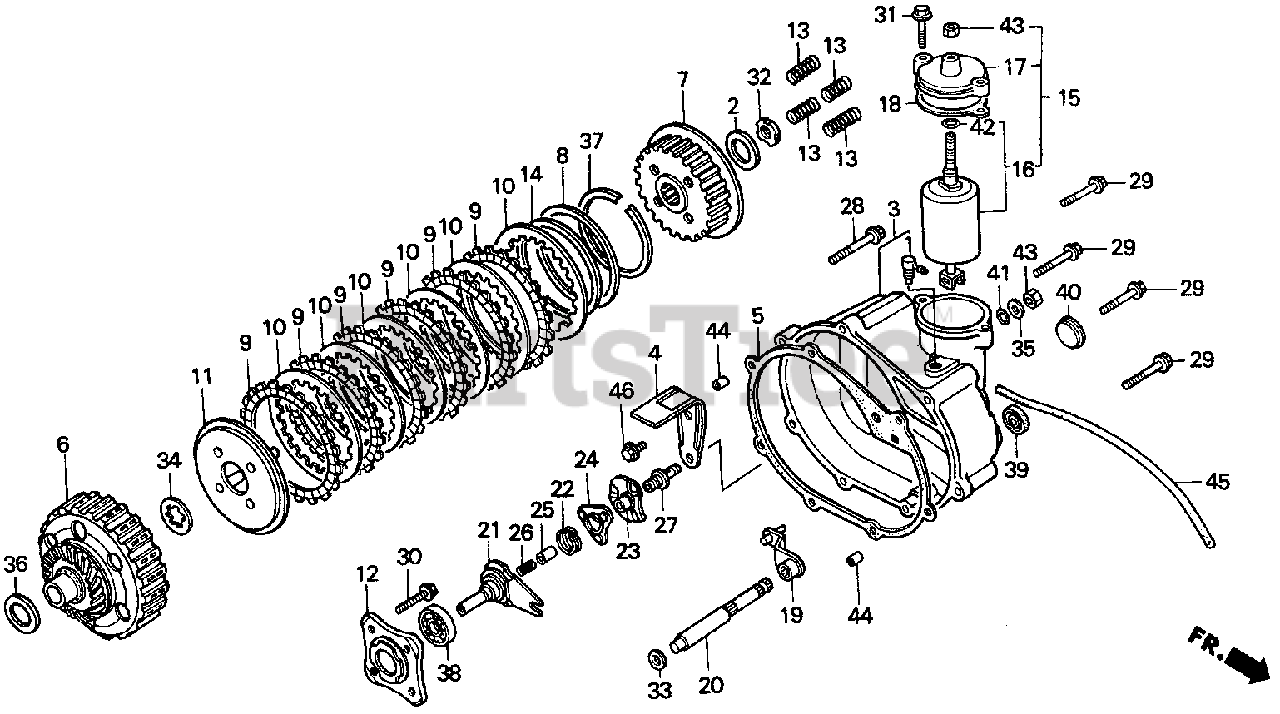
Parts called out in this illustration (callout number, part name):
1	JOINT, BREATHER
2	WASHER, OIL FILTER ROTOR LOCKING
3	COVER, CLUTCH
4	GUIDE, OIL
5	GASKET, CLUTCH COVER
6	CLUTCH (OUTER)
7	CENTER, CLUTCH
8	SEAT, JUDDER SPRING
9	DISK, CLUTCH FRICTION
10	PLATE, CLUTCH
11	PLATE, CLUTCH PRESSURE
12	PLATE, CLUTCH LIFTER
13	SPRING, CLUTCH
14	SPRING, CONED DISK
15	DAMPER SET, CLUTCH
16	DAMPER ASSY., CLUTCH
17	BRACKET, DAMPER (UPPER)
18	GASKET, CLUTCH DAMPER
19	LEVER, CLUTCH
20	SHAFT, CLUTCH
21	PLATE, CLUTCH CAM
22	SPRING, CAM PLATE SIDE
23	PLATE, CLUTCH LIFTER (NOT AVAILABLE)
24	RETAINER, CLUTCH BALL
25	THROUGH, OIL
26	SPRING, OIL THROUGH
27	BOLT, CLUTCH ADJUSTING
28	BOLT, FLANGE (6X40) (CT200)
29	BOLT, FLANGE (6X32) (CT200)
30	BOLT, SPECIAL FLANGE (6X28) (NOT AVAILABLE)
31	BOLT, FLANGE (6X25) (CT200)
32	NUT, LOCK (16MM)
33	WASHER, THRUST (10MM)
34	WASHER, SPLINE (20MM)
35	WASHER (8MM)
36	SHIM, MAINSHAFT (20.2X30X1.25) (A)
36	SHIM, MAINSHAFT (20.2X30X1.30) (B)
36	SHIM, MAINSHAFT (20.2X30X1.35) (C)
36	SHIM, MAINSHAFT (20.2X30X1.40) (D)
36	SHIM, MAINSHAFT (20.2X30X1.45) (E)
36	SHIM, MAINSHAFT (20.2X30X1.50) (F)
36	SHIM, MAINSHAFT (20.2X30X1.55) (G)
36	SHIM, MAINSHAFT (20.2X30X1.60) (H)
36	SHIM, MAINSHAFT (20.2X30X1.65) (I)
36	SHIM, MAINSHAFT (20.2X30X1.70) (J)
37	SET-RING, SPECIAL (82.5MM) (NOT AVAILABLE)
38	BEARING, RADIAL BALL (16003)
39	OIL SEAL (10X20X5)
40	SEAL, PLUG (25X7)
41	O-RING (8X1.7) (ARAI)
42	O-RING (6.8X1.9)
43	NUT, HEX. (8MM)
44	PIN, DOWEL (8X14)
45	BULK HOSE, VACUUM (5X3000) (5X200)
46	BOLT, FLANGE (6X12)
